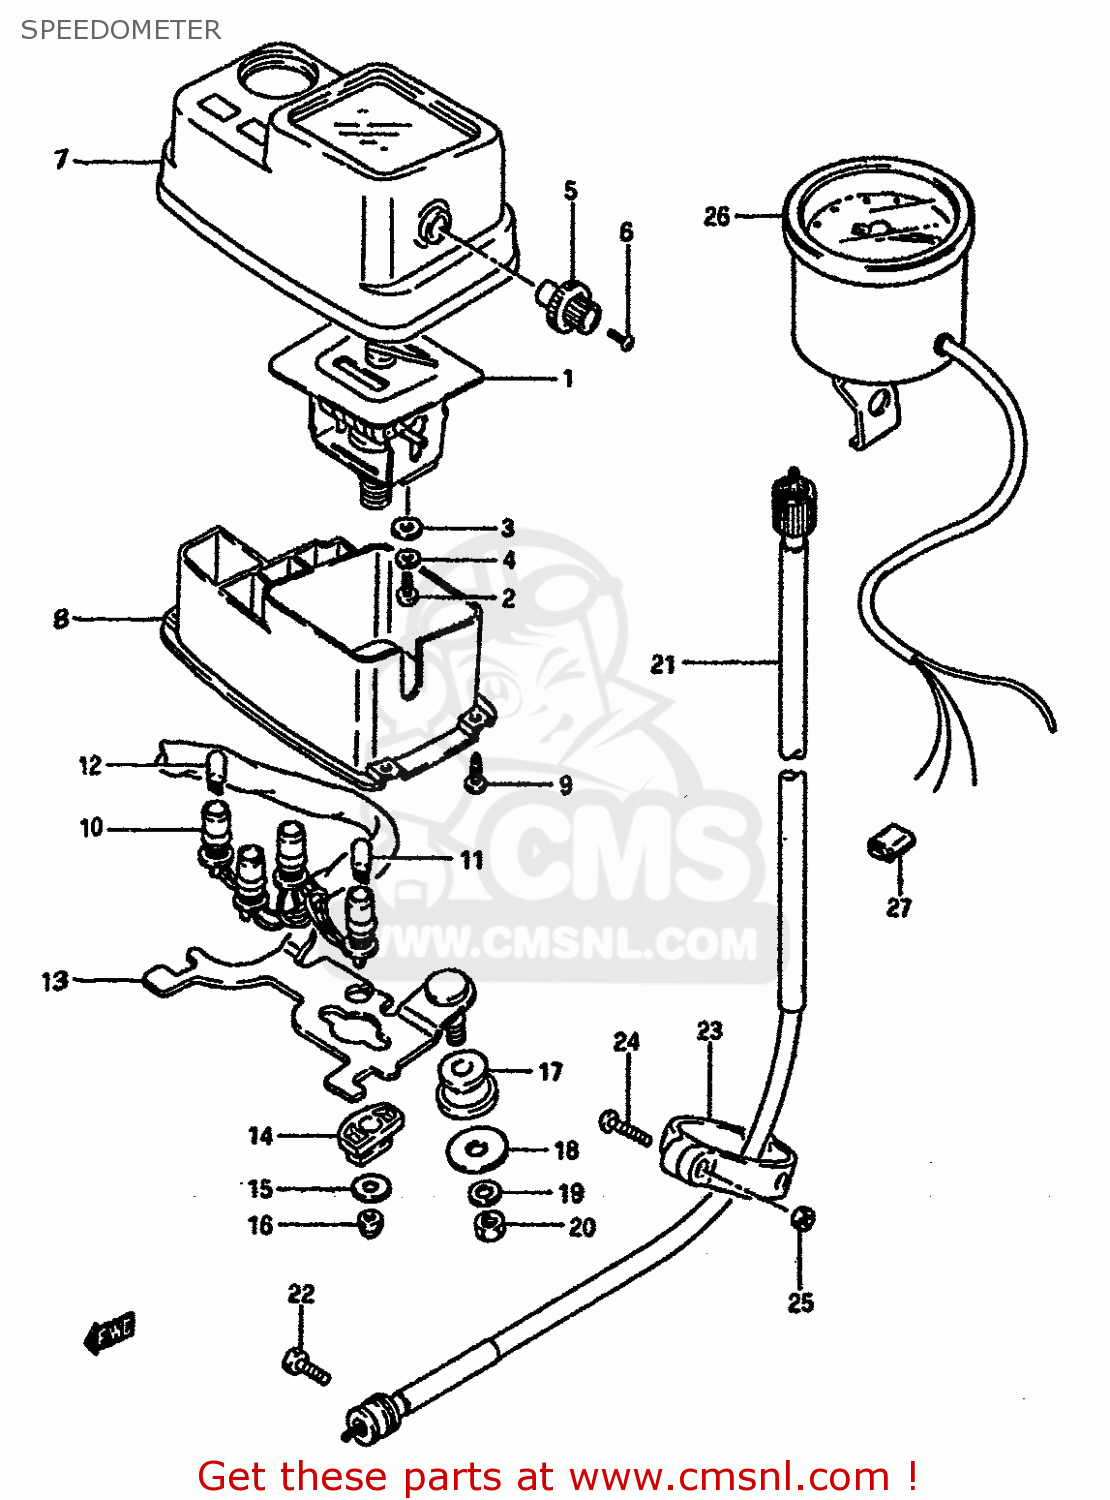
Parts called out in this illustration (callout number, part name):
1	SPEEDOMETER (KILO)
2	SCREW
3	WASHER
4	LOCK WASHER
5	KNOB,TRIP
6	ROTOR,SPEED
7	HOOD,METER
8	CASE,METER
9	SCREW
10	SOCKET,METER
11	BULB(12V3.4W,T10)
12	BULB(12V1.7W,T10,WB121)
13	BRACKET,METER
14	CUSHION
15	WASHER
16	NUT
17	CUSHION,METER BRACKET
18	WASHER (8.5X20X1.6)
19	WASHER,LOCK,8.
20	NUT
21	CABLE ASSEMBLY,SPEEDOMETER
22	BOLT
23	CLAMP,SPEEDOMETER CABLE
24	SCREW 5X20
25	NUT
26	METER,TACHOMETER
27	CONNECTOR,LEAD WIRE
